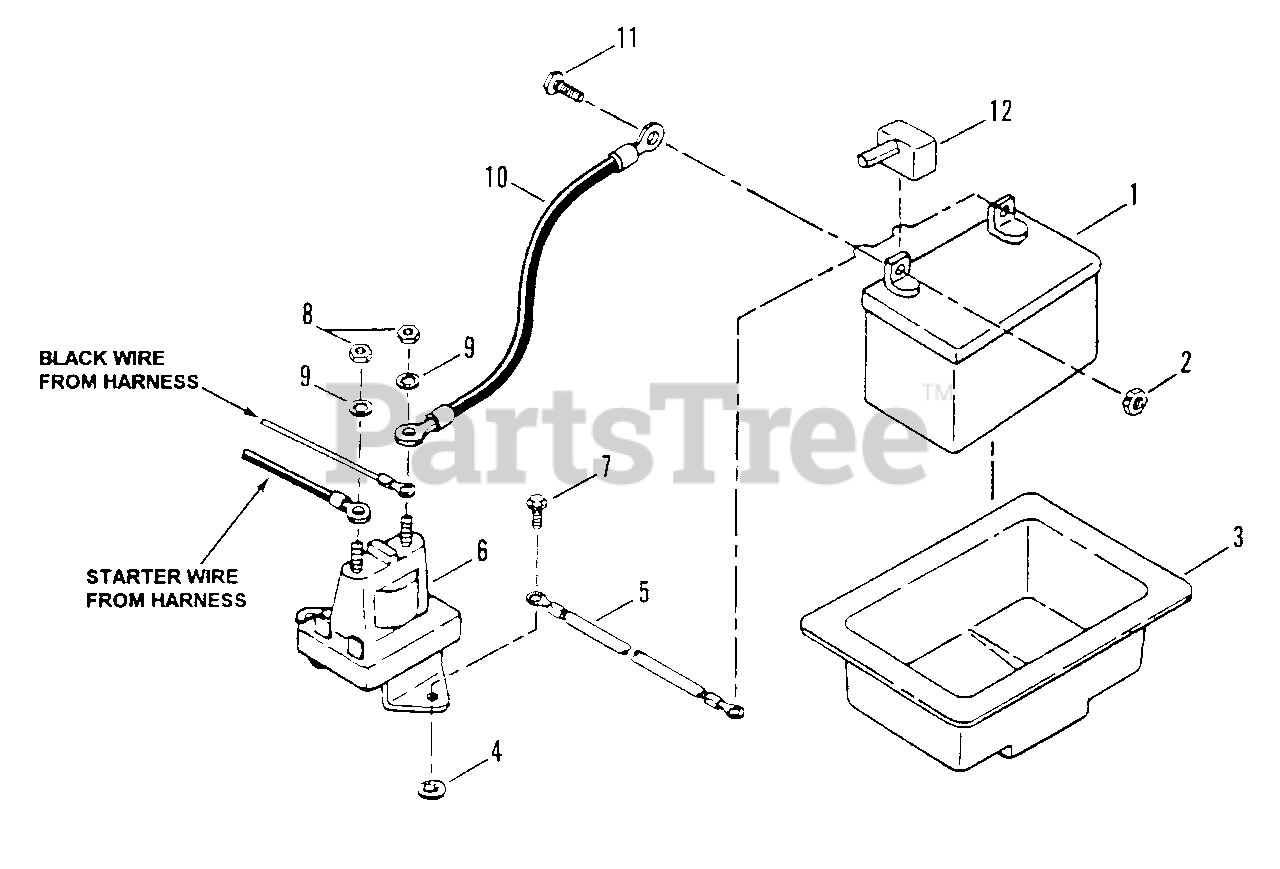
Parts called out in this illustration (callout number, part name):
1	KIT, Battery
2	NUT, 1/4-20 Hex Center Lock
3	TRAY, Battery
4	RETAINER, Screw
5	CABLE, Ground (Black)
6	SOLENOID
7	SCREW, 1/4-20 x 1/2" Self-Tapping
8	NUT, 1/4-20 Hex Jam
9	WASHER, 1/4 Internal Tooth Lock
10	CABLE, Positive (Red)
11	SCREW, 1/4-20 x 5/8 Hex Head Cap
12	COVER, Positive Terminal
